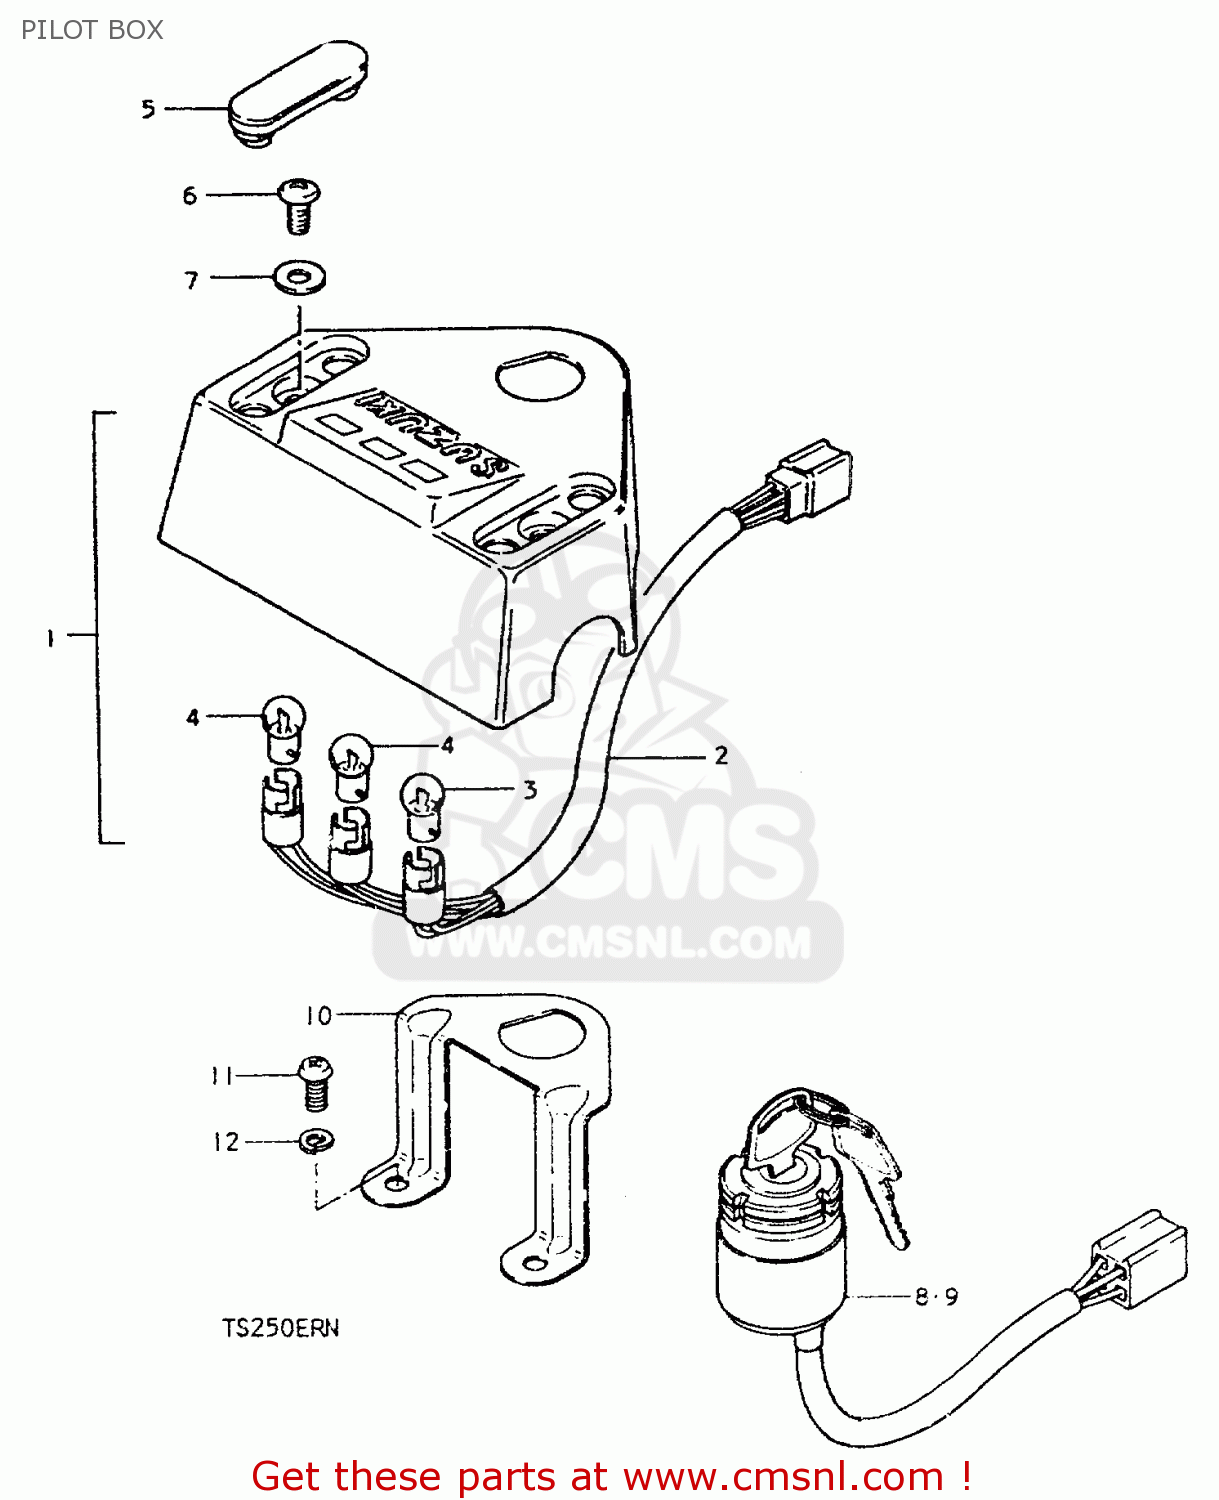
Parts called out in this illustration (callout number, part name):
1	CASE,PILOT BULB
2	SOCKET
3	BULB(6V1.7W,STANLEY,A61A)
4	BULB(6V/3W)
5	CAP,PILOT BOX BOLT
6	SCREW 6X12
7	WASHER
9	SWITCH ASSY, IGNITION
10	BRACKET,IGNITION SWITCH
11	SCREW
12	LOCK WASHER
